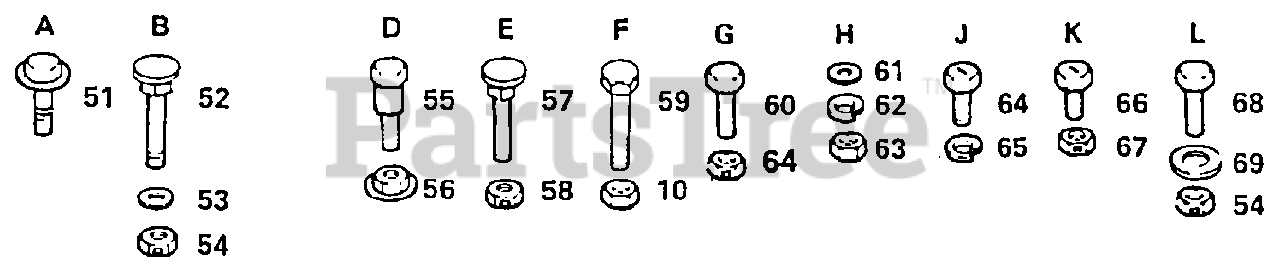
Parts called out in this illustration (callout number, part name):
51	SCREW LT
52	BOLT
53	WASHER
55	SHOULDER BOLT T
56	NUT T
57	BOLT
58	LOCKNUT
59	BOLT
60	BOLT
61	WASHER PM
68	BOLT
69	WASHER PM
